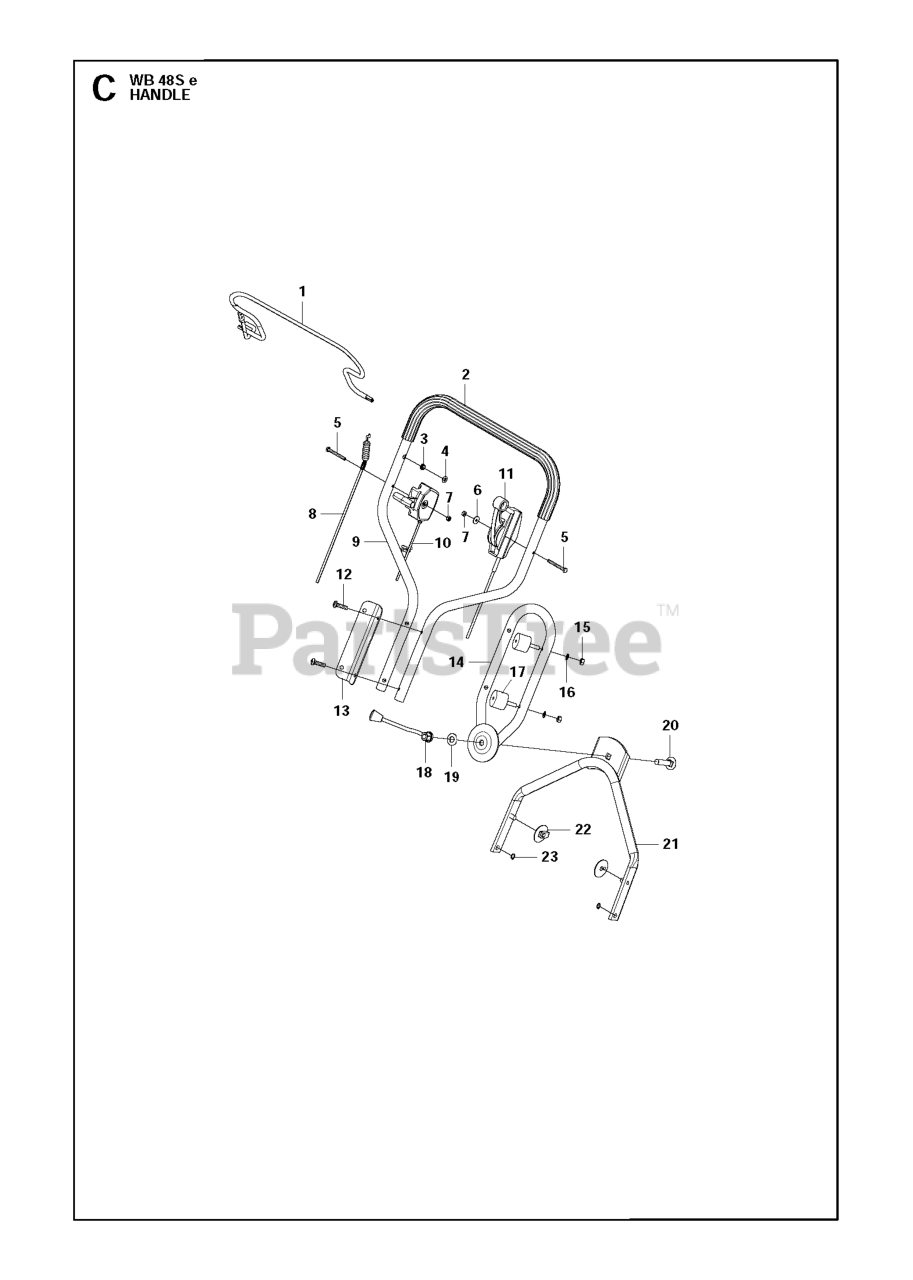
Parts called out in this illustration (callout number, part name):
5	SCREW M6X55
7	NUT FLANGE - M6
15	NUT
23	RETAINING RING SGA 10
